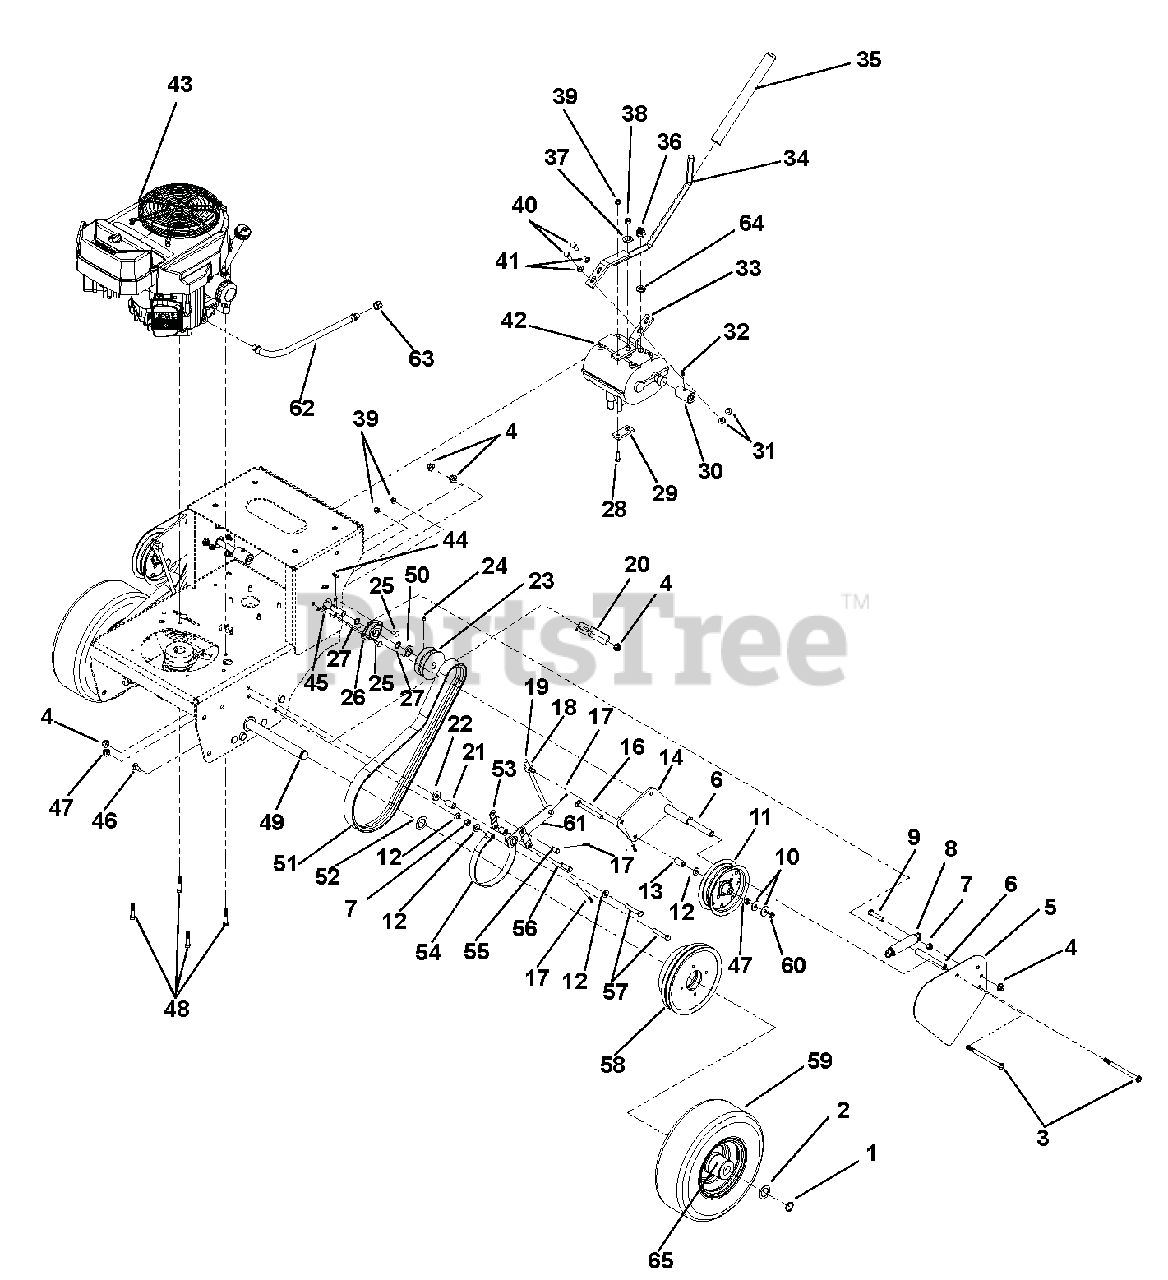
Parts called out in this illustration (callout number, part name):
1	RG-RTNG-EXT 1.00X.078
2	WSHR-FL-STL 1.010X1.505X.062YZ
3	BOLT, 3/8-16X5.00 HEX 5 Y
4	@NUT-LK-NYL-FLG .38-16 YWZC
5	COVER, TRACTION BELT
6	BUSH.,S.385X.610X4.32 ST
7	NUT, 3/8-16 STD HEX GR5 Y
8	SG-TENS .105X1.00X5.0
9	BOLT, 3/8-16X1.75 HEX 5 Y
10	WSHR-FL-STL .375X1.125X.065YWZ
11	ASM, IDLER 4"
12	WASHER, .406X.813X.065 FLAT Y
13	BSHG-SLV .375X.625X.1.000
14	WMT - WHEEL CLUTCHING ARM -LH
15	WMT - WHEEL CLUTCHING ARM - RH
16	@BLT-RDHDSQNK .38-16X3.50 G5YZ
17	PIN-HAIR, ENDRIES #25 YWZC
18	SWIVEL, 3/8-24
19	ROD, BRAKE ACTUATING
20	PLATE, BENT BELT FINGER
21	BUSH.,S.391X.622X.950 ST
22	WSHR-FL-STL .406X1.00X.188 YWZ
23	SHEAVE-DRIVE 3.25 OD X .625 ID
24	SCR-SET .31-18X.38 SKHCUPDL
25	BOLT, 1/4-20X.750 CRG 5 Y
26	BRG-FLG .625X1.875X.797
27	RG-RTNG-EXT .579X.035
28	BOLT, 1/4-20X1.00 HEX 5 Y
29	PLATE, SHIFT
30	COUPLER
31	@NUT-LK-NYL-FLG .31-18 YWZC
32	FTG, 1/4-28 STRGT GREASE ZERK
33	BRACKET, SHIFT LEVER
34	WMT, SHIFT LEVER
35	GRIP, HANDLEBAR
36	SWITCH-NEUTRAL START N.O.
37	WSHR-LK .375X.130 YWZC
38	NUT-LK-CTR .375-24 YWZC
39	@NUT-LK-NYL-FLG .25-20 YWZC
40	BOLT, 5/16-18X3.25 HEX 5 Y
41	@WSHR-FL-STL.344X.688X.065YWZC
42	TRANSMISSION
43	ENGINE, KAWASAKI FS481
44	KEY-WDRF .19X.75 HRD #9
45	SHAFT, HALF
46	BOLT, 3/8-16X.750 CRG 5 LN Y
47	LOCKNUT, 3/8-16 CENTER Y
48	BLT-HEX.38-16X1.25FTHG5 EP30YZ
49	SHAFT, AXLE
50	WSH, FLT .765"X.1.125"X.187"
51	BELT, GEAR DRIVE 49" EL COG
52	WSHR-HRD-THRS 1.007X1.542X.062
53	LINK,BRAKE ARM
54	ASM, BRAKE BAND, PRO
55	PIN, CVS .375X.750X.516 Y
56	PIN-CLEV .38X1.25 YWZC
57	BOLT, 3/8-16X2.00 HEX 5 Y
58	ASSY, PULLEY & DRUM
59	ASSY, WHEEL AND TIRE 6X4.5
60	@NUT-LK-CTR-JAM .375-16 YWZC
61	WMT, BRAKE ACTUATING LEVER
62	DRAIN, M20 OIL
63	PIPE CAP 3/8 NPT FEMALE
64	WSHR-FL-STL, .563X1.00X18 GA
65	BEARING, 1" SEALED
